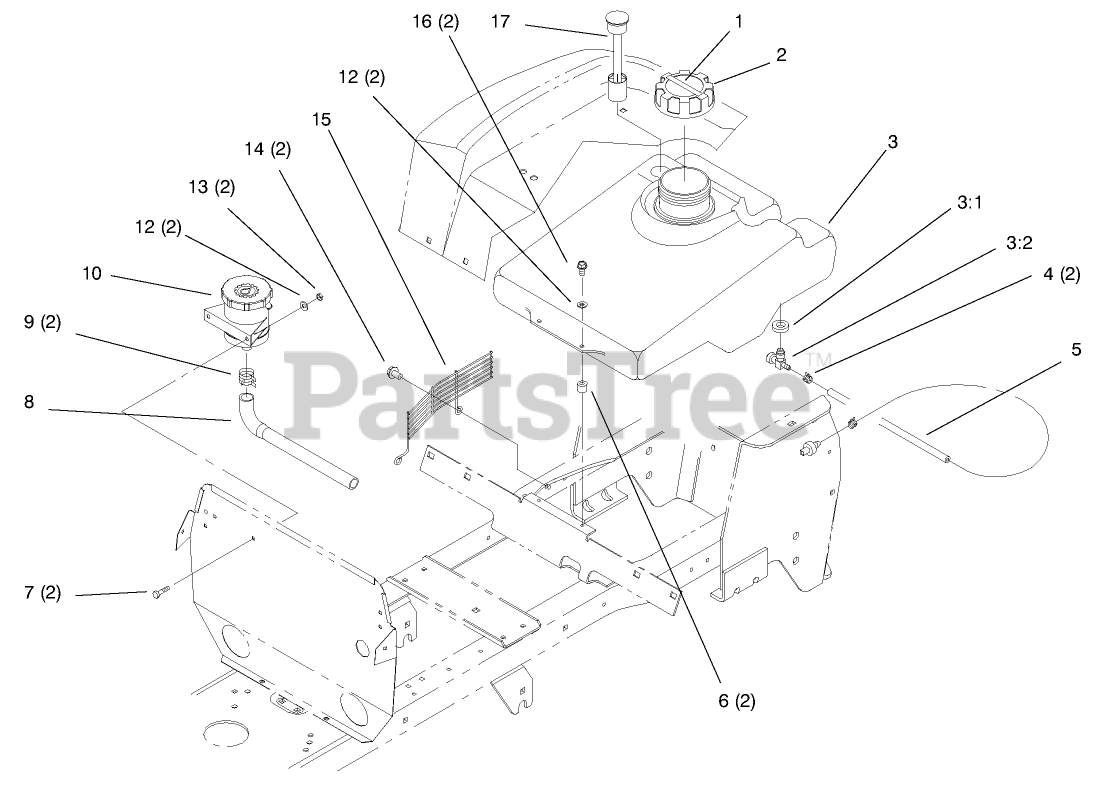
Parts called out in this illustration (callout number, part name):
2	GAS CAP ASM
3	TANK-GAS (FG50538)
3:2	VALVE-FUEL
4	CLAMP-HOSE
6	SPACER - FUEL TANK
7	SCREW-HH
8	HOSE - HYDRO
9	CLAMP-HOSE
12	WASHER-FLAT
13	NUT-LOCK, NI
14	SCREW-HWHTF
16	SCREW-HH
